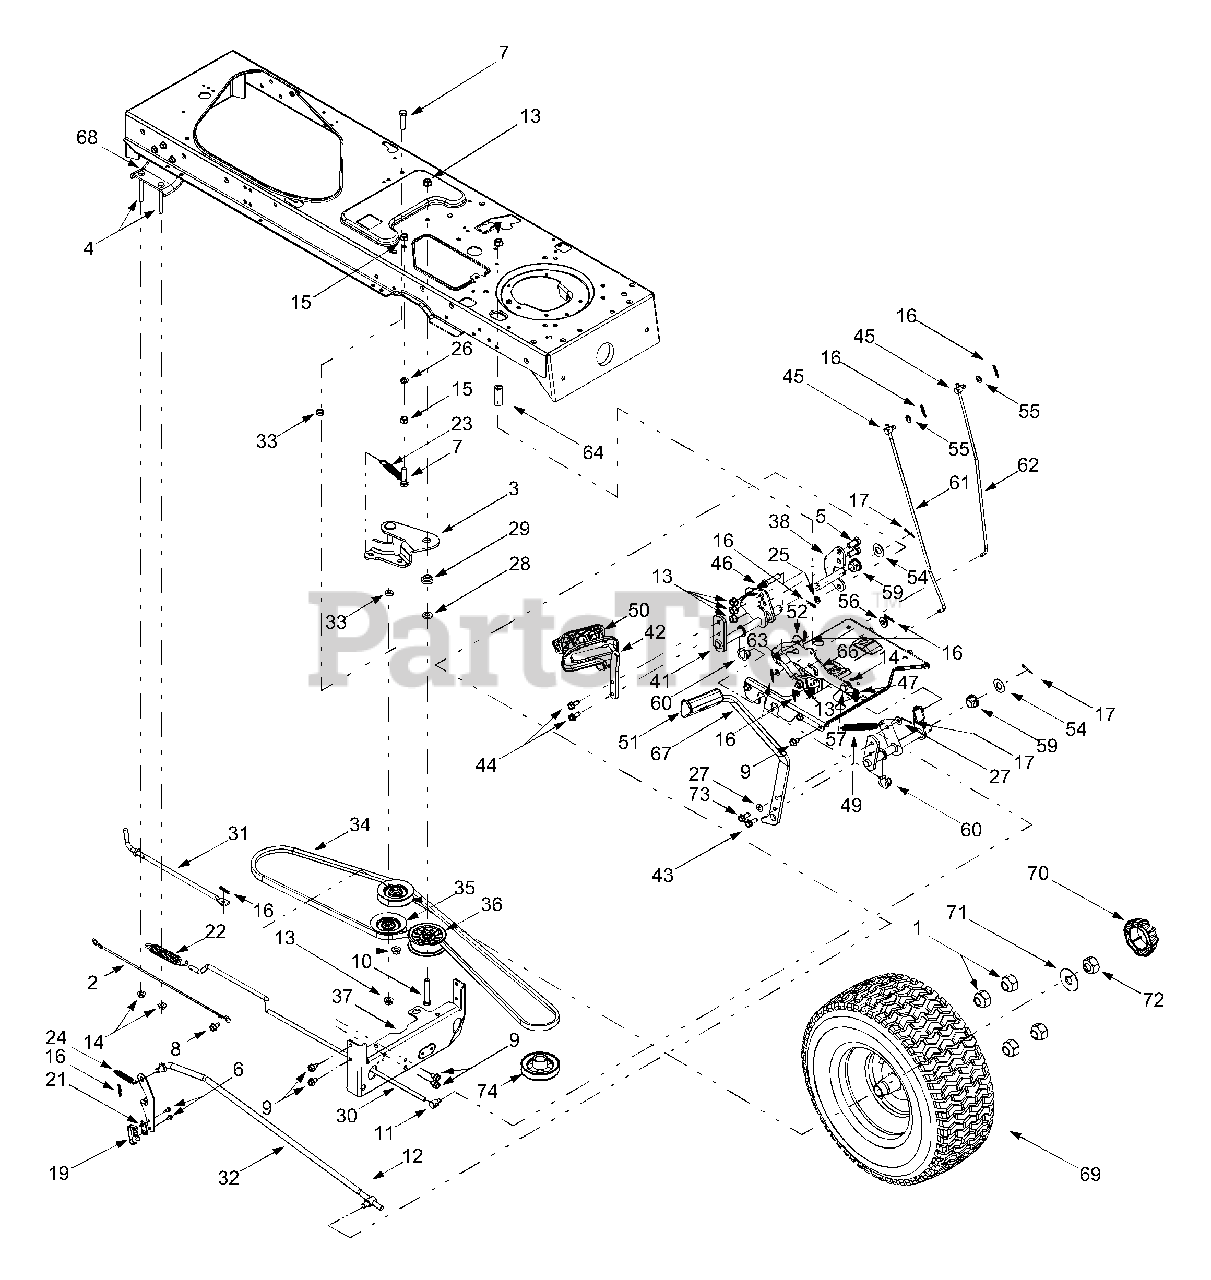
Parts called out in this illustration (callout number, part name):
1	Lug Nut, 3/4-16
2	Reverse/Ground Wire Harness Adapt
3	Double Idler Bracket Assembly
4	Hex Cap Screw, 5/16-18 x 2.75
5	Hex Cap Screw, 3/8-16 x .75
6	Screw, #8-18 x .5
7	Hex Cap Screw, 3/8-16 x 1.5
8	Self-tapping Screw, 1/4-20 x .50
9	Self-tapping Screw, 5/16-18 x .625
10	Hex Cap Screw, 3/8-16 x 2.25
11	Ferrule, 5/16-18
12	Ferrule, 3/8-24
13	Flange Lock Nut, 3/8-16
14	Flange Lock Nut, 5/16-18
15	Hex Nut, 3/8-16
16	Internal Cotter Pin
17	Cotter Pin
18	Cable Tie
19	Short Spring Switch
20	Push-mount Cable Tie
21	Insulator Nut Plate
22	Extension Spring, .59 x 4.0
23	Extension Spring, .5 x 3.97
24	Extension Spring, 3/8 x 1.44
25	Flat Washer, .385 x .62 x .063
26	Lock Washer, 3/8
27	Flat Washer, .344 x .750 x .120
28	Flat Washer, .407 x .812 x .135
29	Shoulder Spacer, .38
30	Hydrostatic Control Rod
31	Hydrostatic Bypass Rod
32	Hydrostatic Brake Rod
33	Spacer, .376 x .625 x .22
34	Drive Belt
35	V-idler Pulley, 3.06
36	Flat Idler Pulley, 2.75
42	Hydro Pedal Assembly
43	Self-tapping Screw, 5/16-18 x .875
44	Self-tapping Screw, 5/16-18 x .75
45	Ferrule, 1/4-20
46	Pin, 3/8-16 x 2.43
47	Compression Spring, .40 OD x 1.17
48	Extension Spring, .50 OD x 1.41
49	Extension Spring, .50 OD x 6.37
50	Drive Pedal Pad
51	Brake Pedal Pad
52	Flat Washer, .411 x 1.25 x 1.0
53	Flat Washer, .281 x .50 x .063
54	Flat Washer, .64 x 1.24 x .06
55	Flat Washer, .344 x .062 x .03
56	Flat Washer, .406 x .875 x .105
57	Shoulder Screw, .437 x 1.62
58	Shoulder Screw, .5 x .434
59	Hex Flange Bearing
60	Split Hex Flange Bearing
61	Cruise Control Rod
62	Brake Lock Control Rod
63	Cruise Latch
64	Spacer, 5/16 x 1.54
66	Drive Lockout Bracket
70	Hub Cap
71	Flat Washer, .780 x 1.59 x .062
72	Jam Nut, 3/4-16
73	Self-tapping Screw, 5/16-18 x .75
74	Engine Pulley
